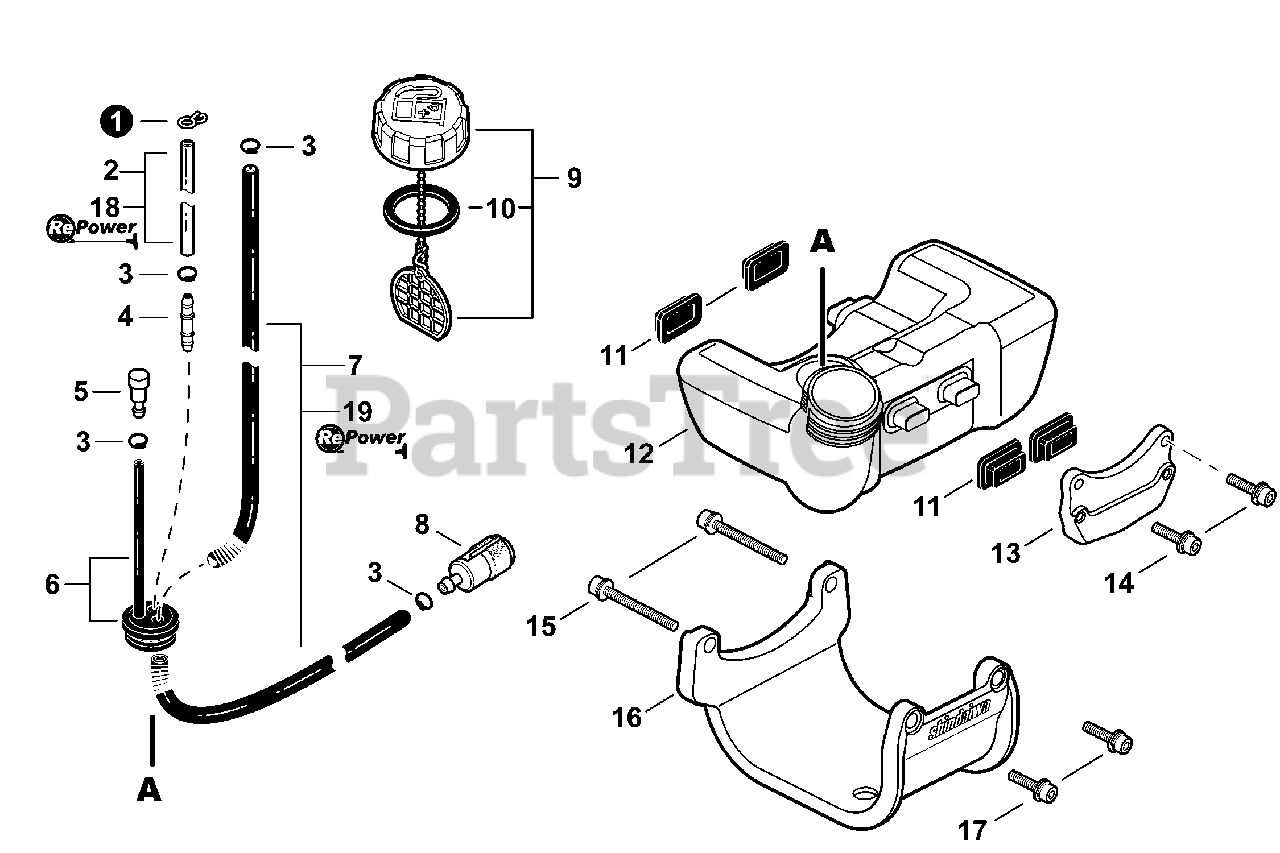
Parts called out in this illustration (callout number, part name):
1	CLIP, SPRING Ø5.2
2	PIPE, FUEL RETURN
3	CLIP Ø6
4	CONNECTOR, PIPE
5	VENT ASSY
6	GROMMET, FUEL W/VENT PIPE
7	PIPE, FUEL 3.3×6×160
8	FILTER, FUEL 125-528
9	CAP ASSY, FUEL
10	GASKET, FUEL CAP
11	CUSHION, FUEL TANK
12	TANK, FUEL
13	BRACKET, METAL FUEL TANK
14	BOLT, ADHESIVE M5×20
15	BOLT M5×40
16	GUARD, PLASTIC FUEL TANK
17	BOLT M5×20
18	BULK PIPE - 3×6 MM CLEAR (4 PIECES×2 M)
19	BULK PIPE - 3×6 MM BLACK (4 PIECES×2 M)
